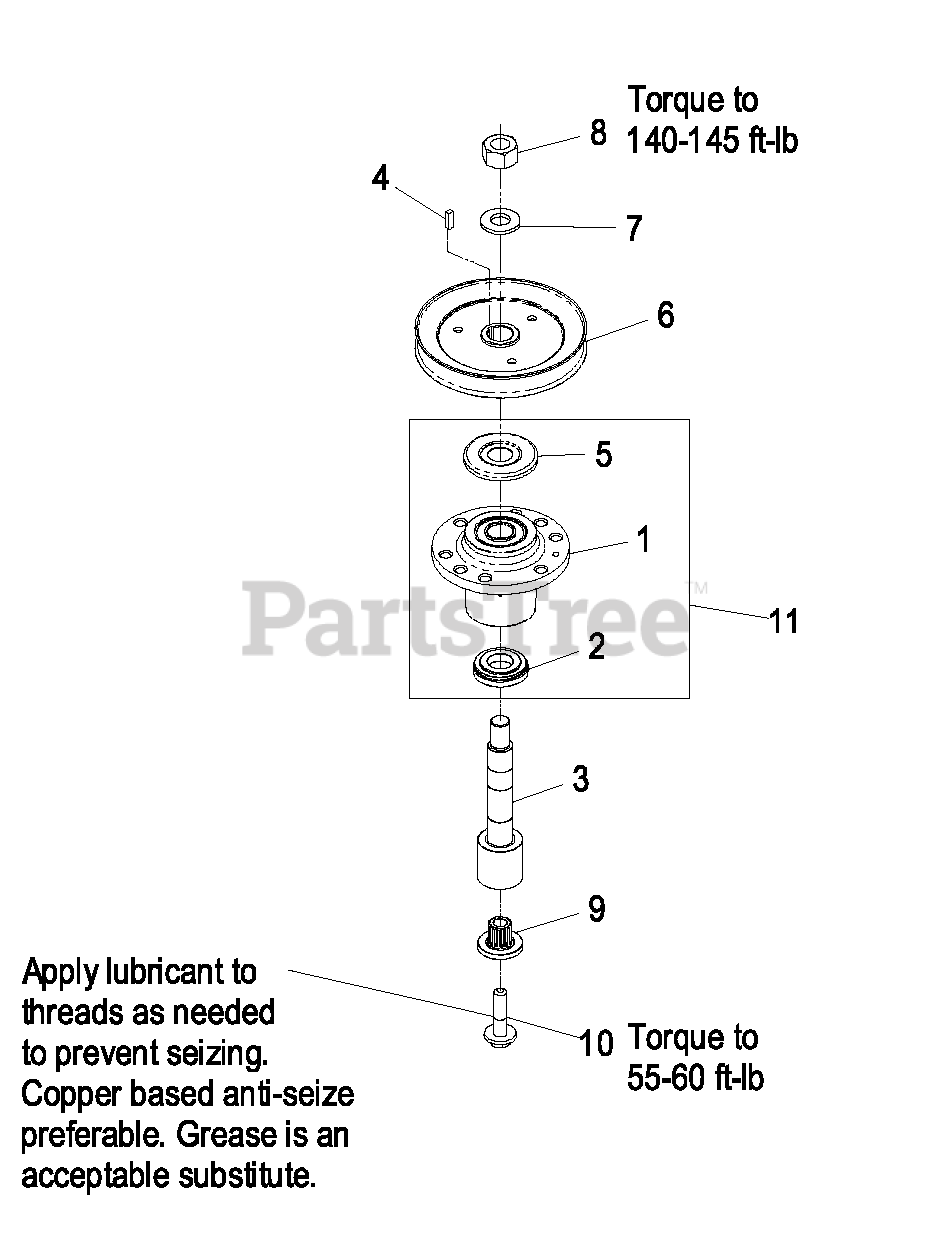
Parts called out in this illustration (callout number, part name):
2	SPACER-GUARD, BOTTOM
3	KIT, SPLINED SPINDLE 103-
5	GUARD-BEARING, TOP
6	SHEAVE,BLADE DRIVE
9	BUSHING,SPLINED
10	SCREW,SEMS 1/2-20 X 2.19
11	KIT, CUTTER HOUSING
